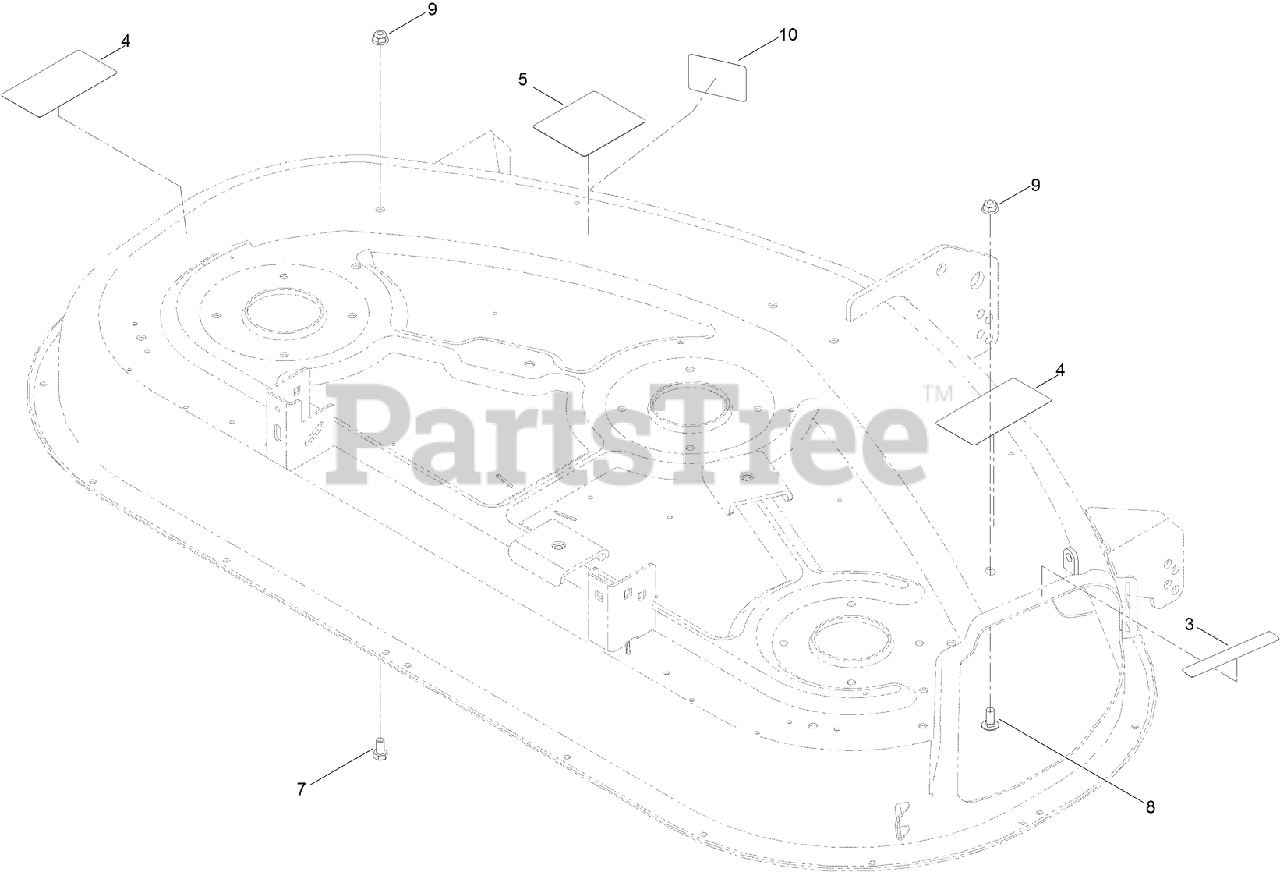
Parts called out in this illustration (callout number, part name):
3	DECAL-DANGER
4	DECAL-DANGER, DECK
5	DECAL-ROUTING, BELT
7	SCREW-HH
8	SCREW-CARR
9	NUT-HF, NI
10	DECAL-SCALP, ANTI
